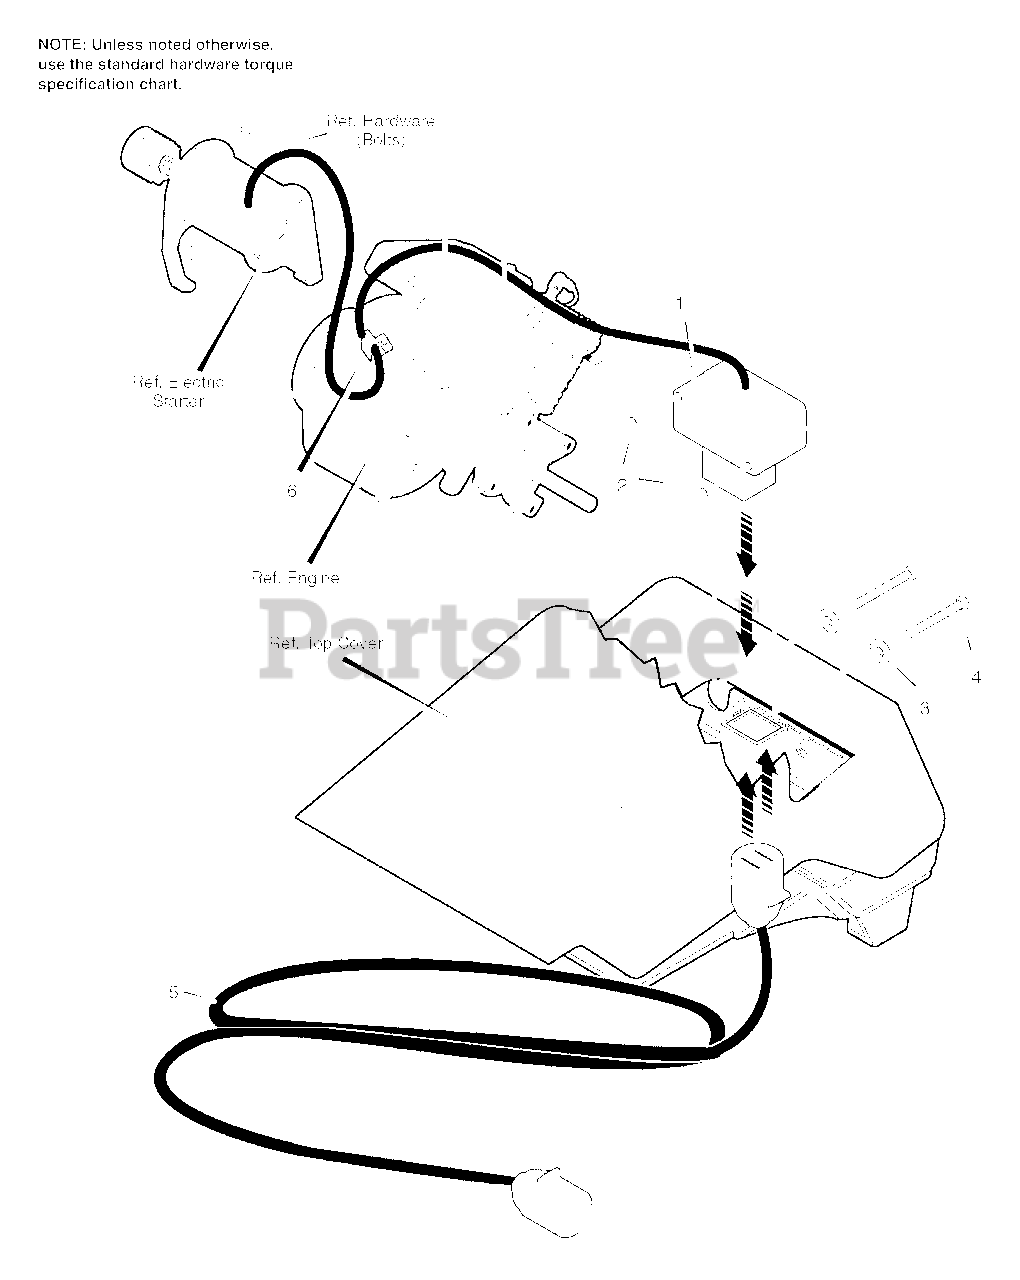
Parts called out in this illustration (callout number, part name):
1	ELECTRIC STARTER
2	NUT, KEPS 8-32
3	WASHER, FLAT
4	SCREW 8-32 x 3.00
5	CORD, EXTENSION
6	STARTER CORD RETAINER
